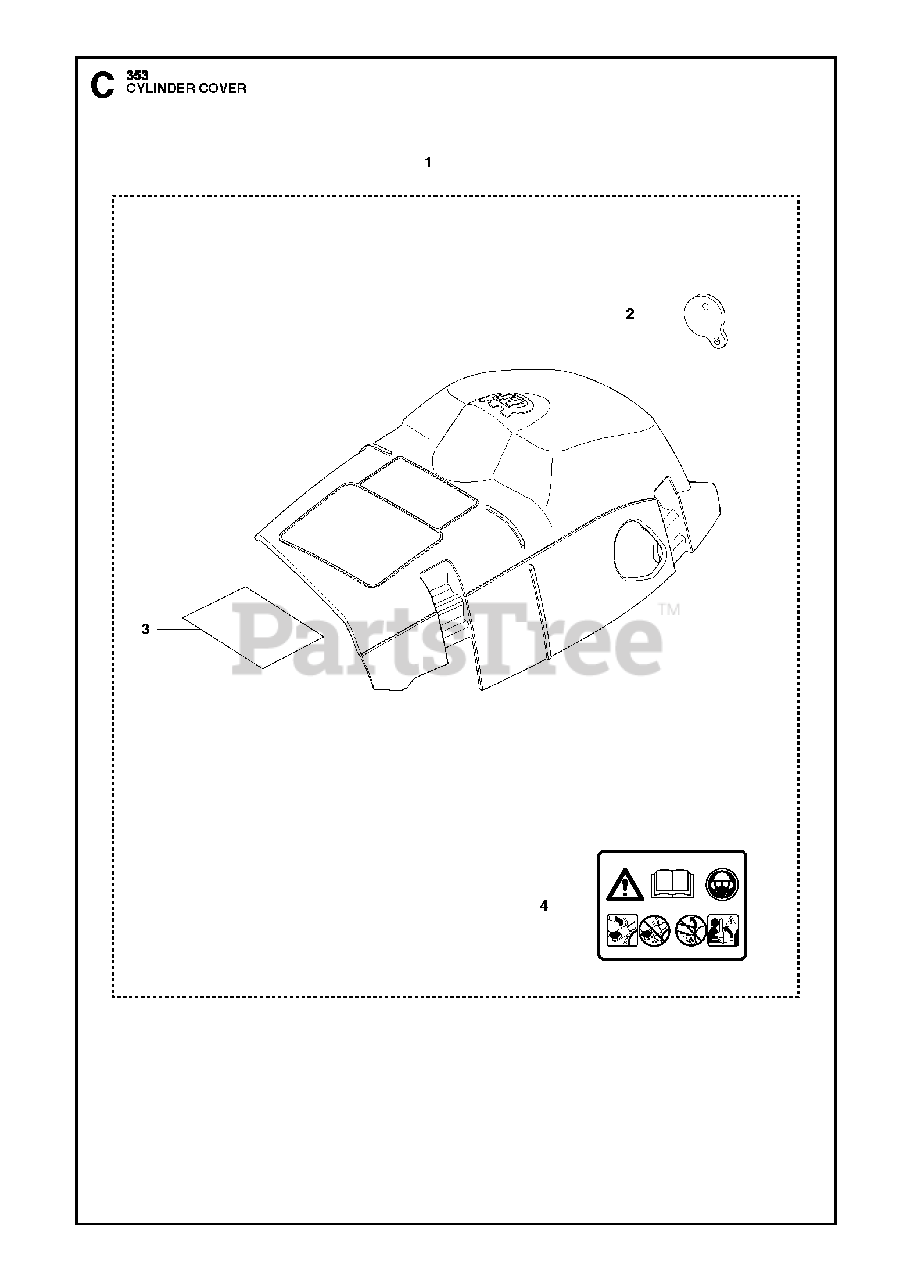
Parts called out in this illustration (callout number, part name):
1	CYLINDER COVER ASSY
2	COVER
3	INSULATING FOIL/CYLINDER COVER
4	DECAL
